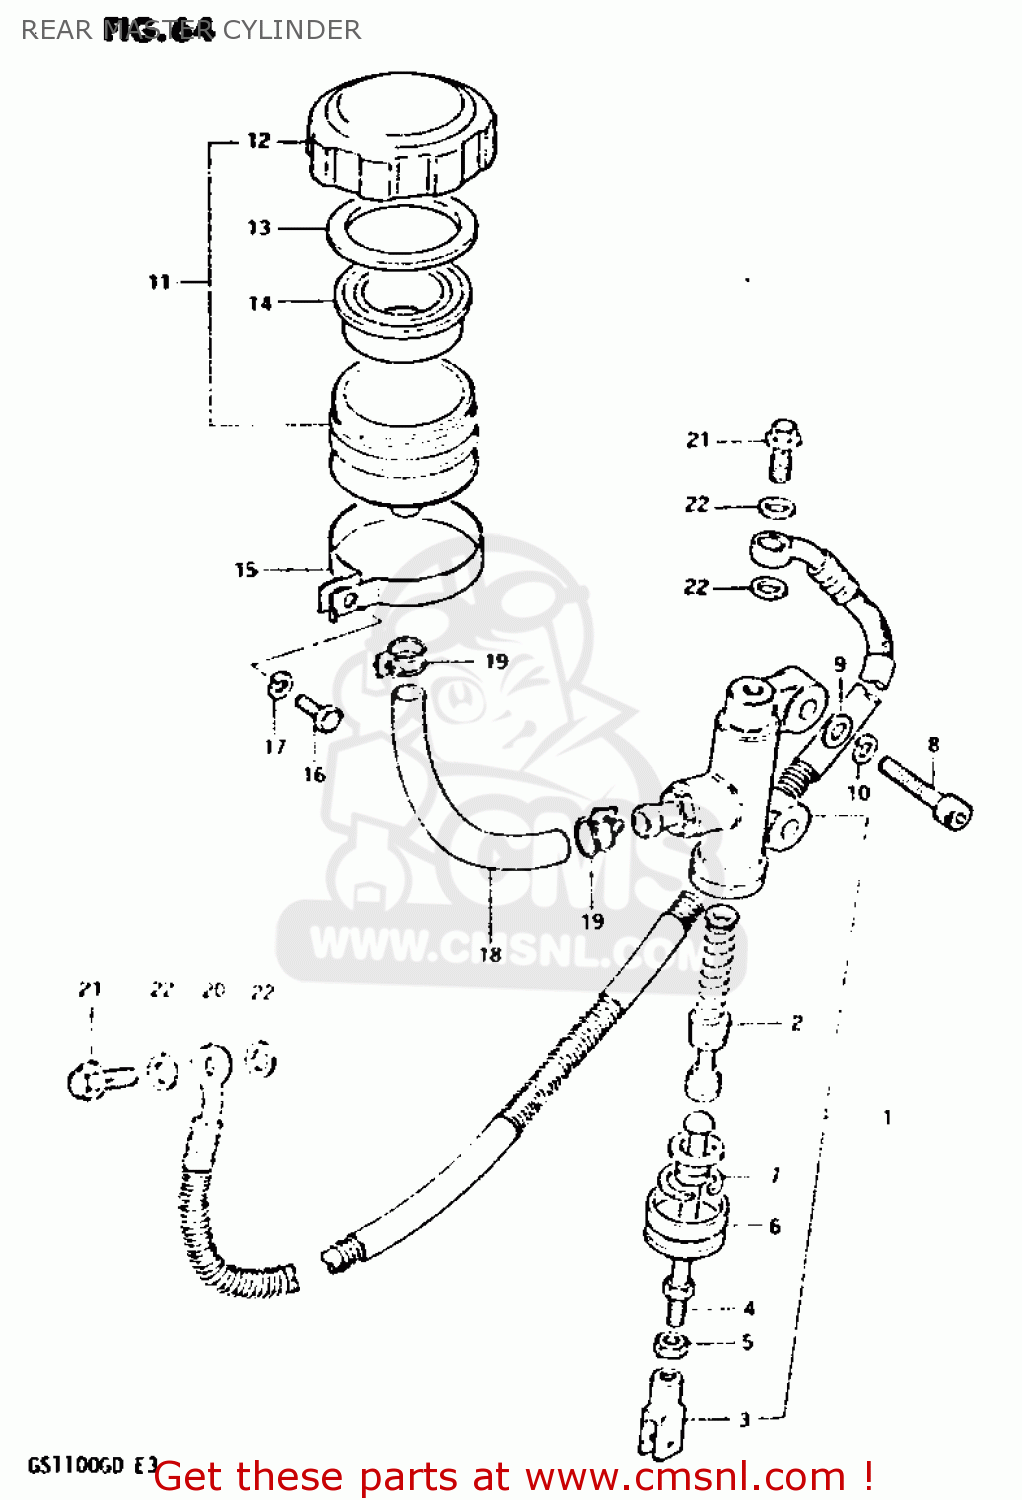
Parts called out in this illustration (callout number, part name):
1	CYLINDER ASSY,RR MASTER
2	PISTON/CUP SET
3	YOKE
4	ROD,REAR MASTER CYLINDER
5	NUT,MASTER CYLINDER
6	BOOT
7	CIRCLIP
8	BOLT, REAR (8X30)
9	WASHER
10	WASHER,LOCK
11	TANK ASSEMBLY,RESERVOIR
12	CAP
13	PLATE,DIAPHRAGM
14	DIAPHRAGM
15	CLAMP
16	BOLT
17	WASHER,LOCK
18	HOSE,RESERVOIR TANK
19	CLAMP
20	HOSE,REAR BRAKE
21	BOLT,UNION
22	WASHER(10X15X1.5)
